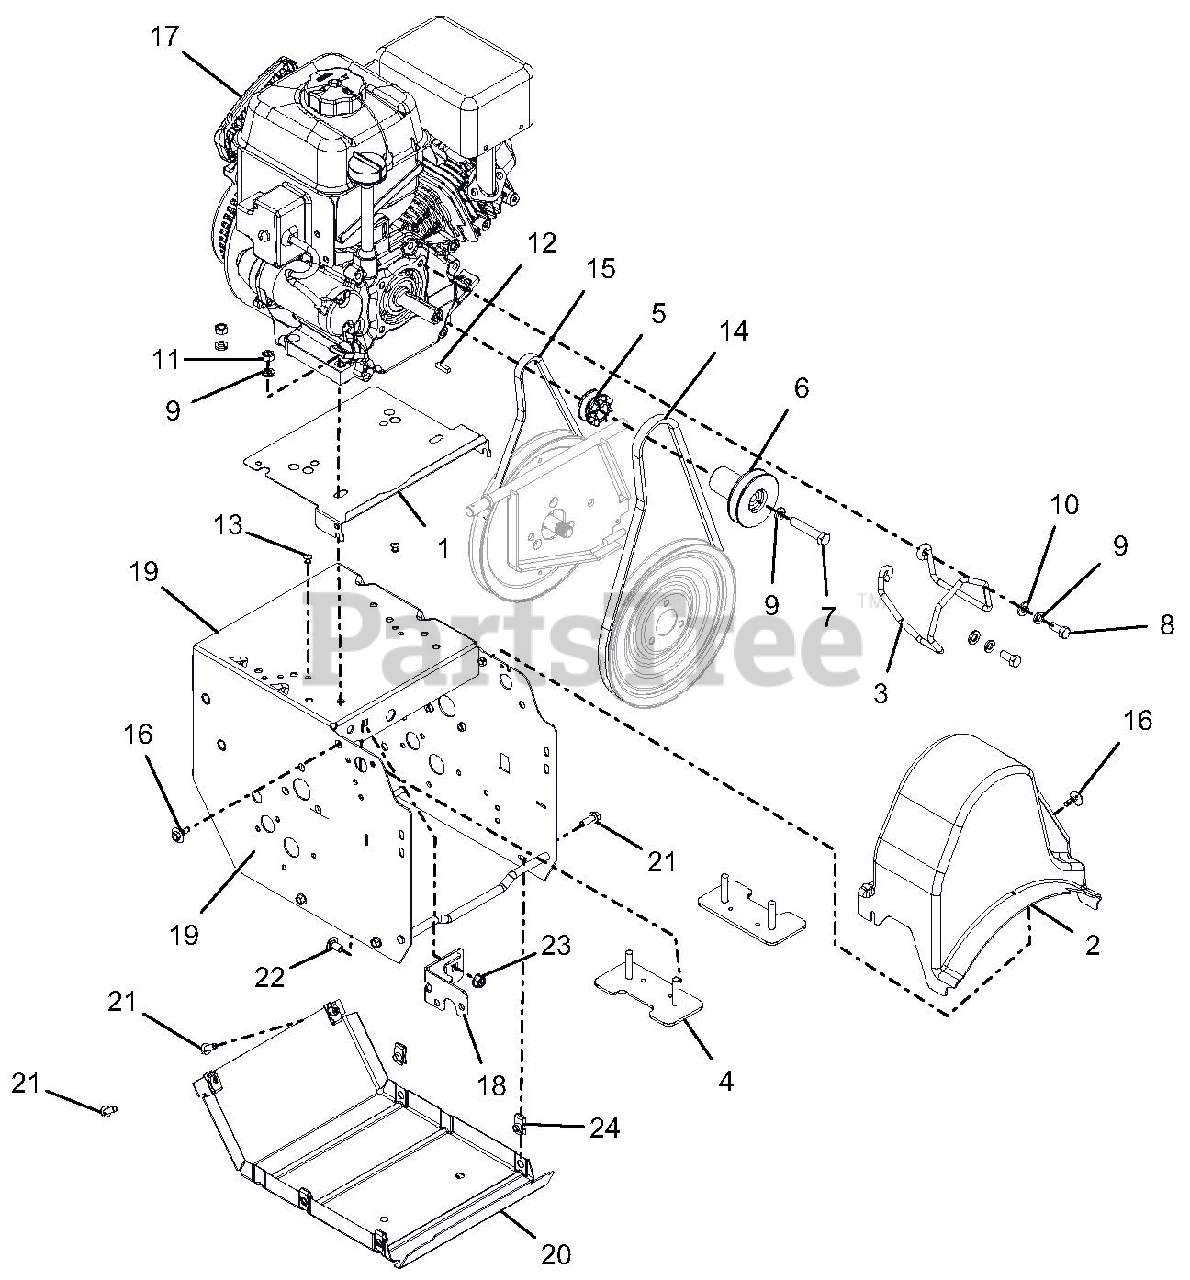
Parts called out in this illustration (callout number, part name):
1	BAFFLE,ENGINE,SMALL BLOCK
2	COVER, COMPACT BELT
3	FINGER, BELT
4	STRAP, ENGINE BOLT-WELDMENT
5	SHEAVE, TRACTION
6	SHEAVE,AUGER 3/4" PM
7	BLT-HEX .38-24X2.0 YWZC
8	BLT-HEX .31-24X.75 YWZC GR5
9	WSHR-LK .312X.097 HVY YWZC
10	@WSHR-FL-STL.344X.688X.065YWZC
11	@NUT-HEX .31-18 YWZC
12	KEY-SQ .188X.75X.188
13	RVT-POP .187 YZ
14	V-BELT, HA-RAW EDGE
15	V-BELT, 3L-WRAPPED
16	SCR-TAP .25-20X.5 CAPTIVE
17	ENGINE, AX208 GEN 2 120V/60W
17	ENGINE, ARIENS 208CC 120V, 60W
17	ENGINE, ARIENS AX208 120V/60W
18	WELDMENT, FRAME BRACKET
19	WELDMENT,FRAME 920
20	COVER, BOTTOM
21	BLT-HEX .25-20X.75 HWH YZ GR5
22	@BLT-RHDSSQNK .31-18X.62 G5YZ
23	@NUT-LK-TOP-FLG .31-18 YWZC
24	NUT-RTNR .25-20X.56
